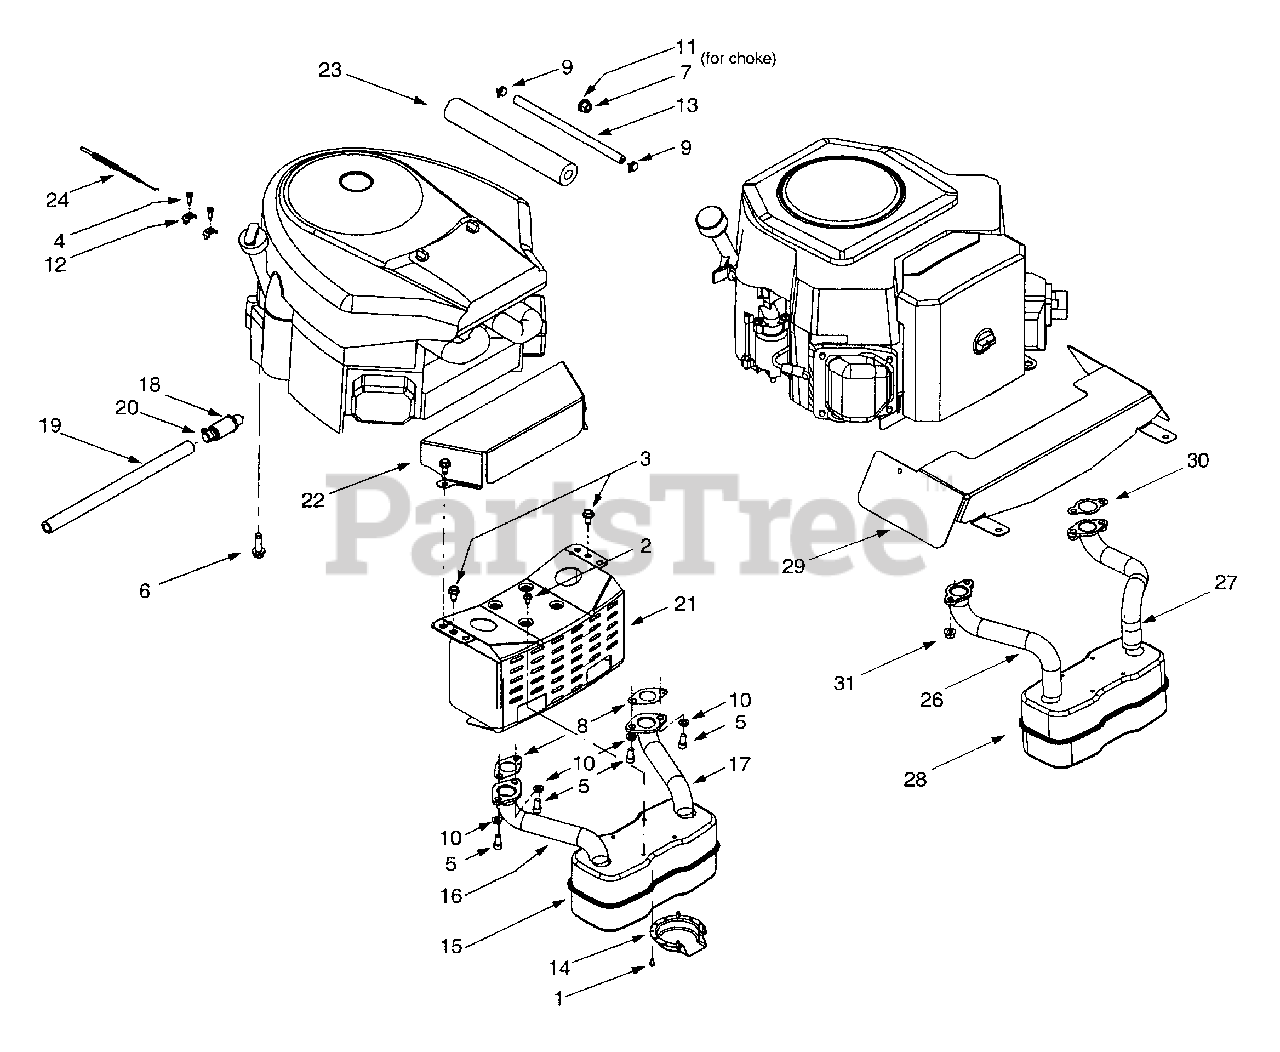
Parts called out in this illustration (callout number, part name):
1	Self-tapping Screw, #8-18 x .5
2	Self-tapping Screw, 1/4-20 x .5
3	Self-tapping Screw, 5/16-18 x .625
4	Screw, #10-32 x .625
5	Socket Cap Screw, 5/16-18 x .625
6	Self-tapping Screw, 3/8-16 x 1.25
7	Hex Nut, 3/8-16
8	Exhaust Gasket
9	Hose Clamp
10	Lock Washer, 5/16
11	Flat Washer
12	Casing Clamp
13	Fuel Line Hose
14	Muffler Deflector
15	Muffler, Twin Inlet
16	RH Exhaust Pipe
17	LH Exhaust Pipe
18	Oil Drain Valve
19	Oil Drain Hose
20	Oil Drain Cap
22	Engine Heat Shield
23	Foam
24	Throttle Cable
26	RH Exhaust Pipe
27	LH Exhaust Pipe
28	Muffler, Twin Inlet
29	Engine Heat Shield
30	Exhaust Gasket
31	Flange Nut, M8 x 1.25-6
